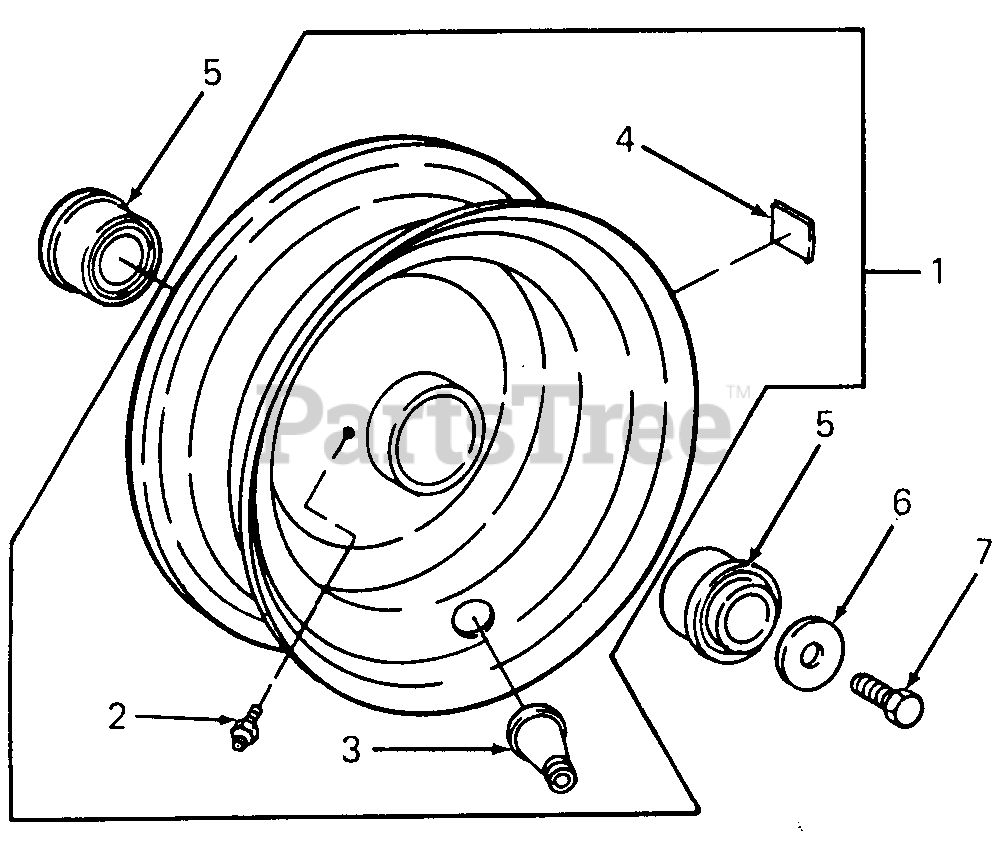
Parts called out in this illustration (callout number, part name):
1	Wheel Assy, Front
2	Fitting, Lube
3	Valve, Tubeless Air
4	Label, Inflation
5	Bearing, Wheel Ball
6	Washer, Flat, .531 x 1.75 x .09 Thk
7	Screw, Hex Cap, 1/2-13 x .75 Lg GR5
